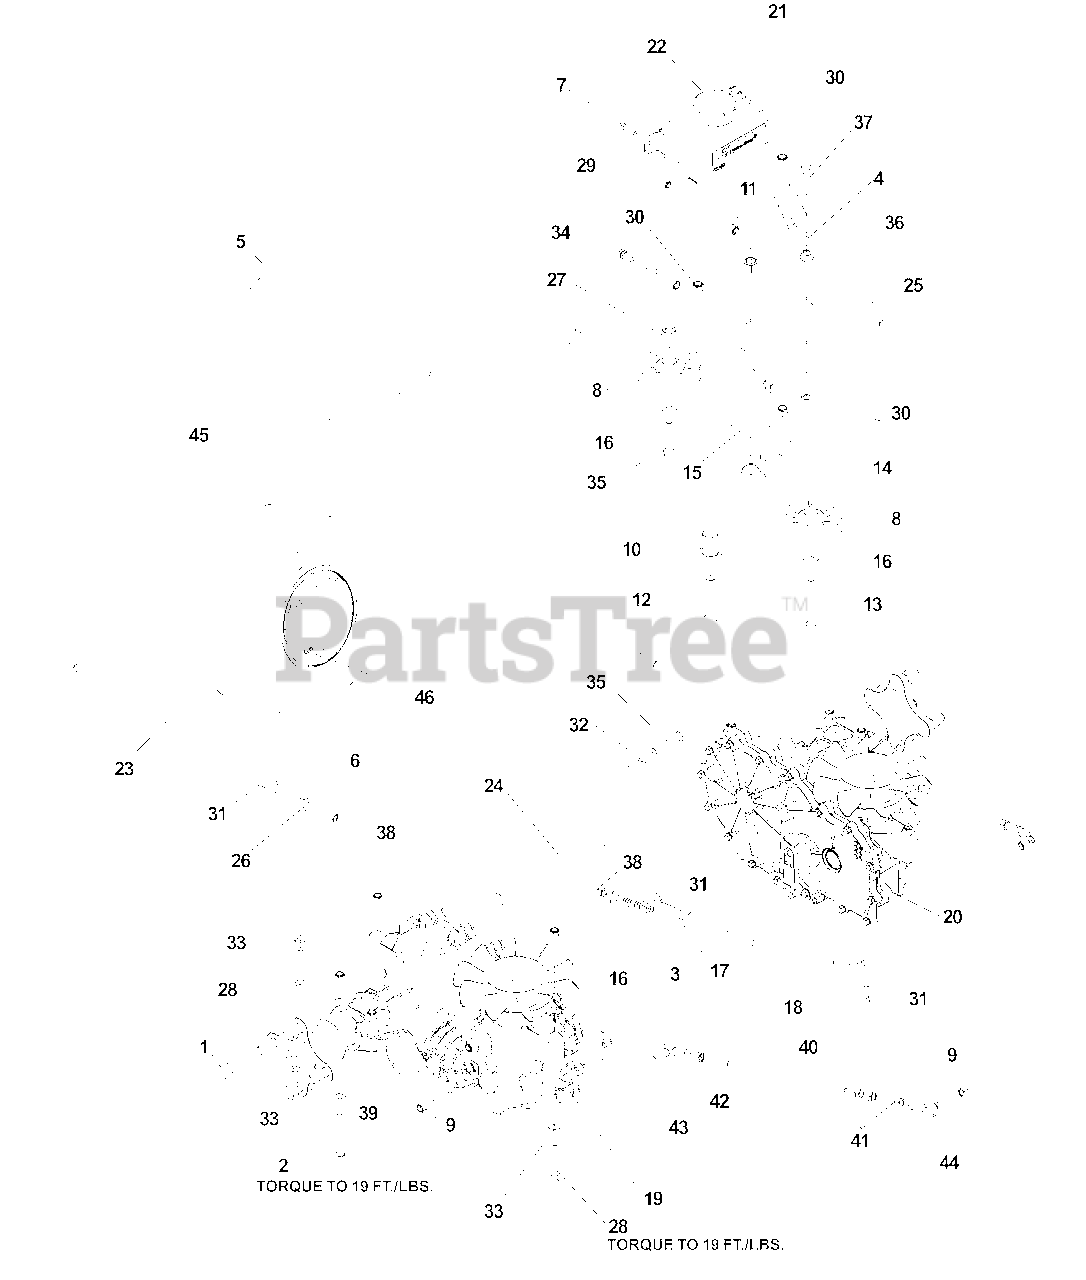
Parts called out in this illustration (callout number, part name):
1	LUG NUT 1/2F
2	HCS 5/16C X 2-3/4
5	PUMP BELT
6	NUT 1/4-28 HEX ZD
7	RHSNB, 1/4-20 X 1, GR5
8	PULLEY, IDLER
9	NUT 5/16F NYLOC
10	IDLER SPINDLE
11	NUT 1/2-13 HEX NYLOC ZD
12	HCS 1/2C X 2 3/4
13	TAPBOLT, 3/8C X 3
14	IDLER ARM WELDMENT
15	HEAVY WASHER
16	WASHER 5/16 FLAT
17	BRAKE SWIVEL
18	BRAKE LINKAGE, LOWER
21	HG_EXPANSION TANK W/CAP
23	BYPASS LINKAGE
24	2800 CROSS SUPPORT
25	IDLER PULLEY PLATE
26	SWIVEL, 1/4-28
28	CAPSCREW
29	NUT 1/4-20 NYLOC
30	NUT 3/8-16 NYLOC
31	HAIRPIN #2
32	SLW 3/8 STD
33	FLAT WASHER 5/16 SAE
34	BOLT 5/16C X 3/4" CARRIAGE
35	HCS 3/8C X 2
36	NUT 3/8C WHIZ
37	HCS 3/8C X 1 1/2
38	NUT 5/16 NYLOC
39	HG_FILTER, ZT4800
40	DRIVE LINKAGE
41	NUT 5/16F
42	NUT 5/16F LEFTHAND
43	SPHERICAL ROD END, LH
44	SPHERICAL ROD END, RH
46	VALVE STEM TR-412
